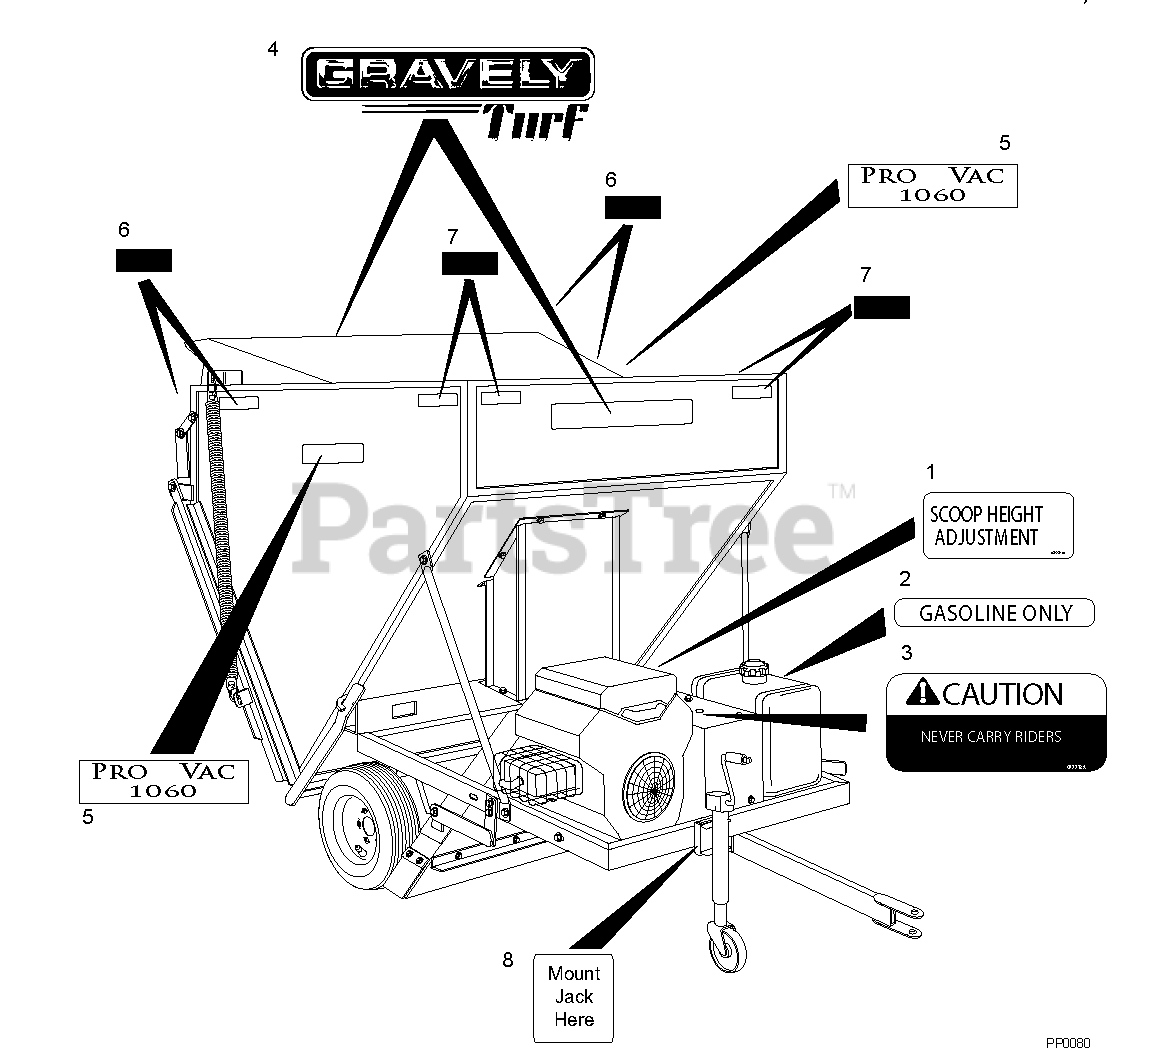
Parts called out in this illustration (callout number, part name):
1	Decal, Scoop Height Adjustment
2	Decal, Gasoline Only
3	Decal, No Riders
4	Decal, 15" Gravely Turf Logo
5	Decal, Pro Vac 1060
6	Reflector, Red
7	Reflector, Amber
8	Decal, Mount Jack Here
